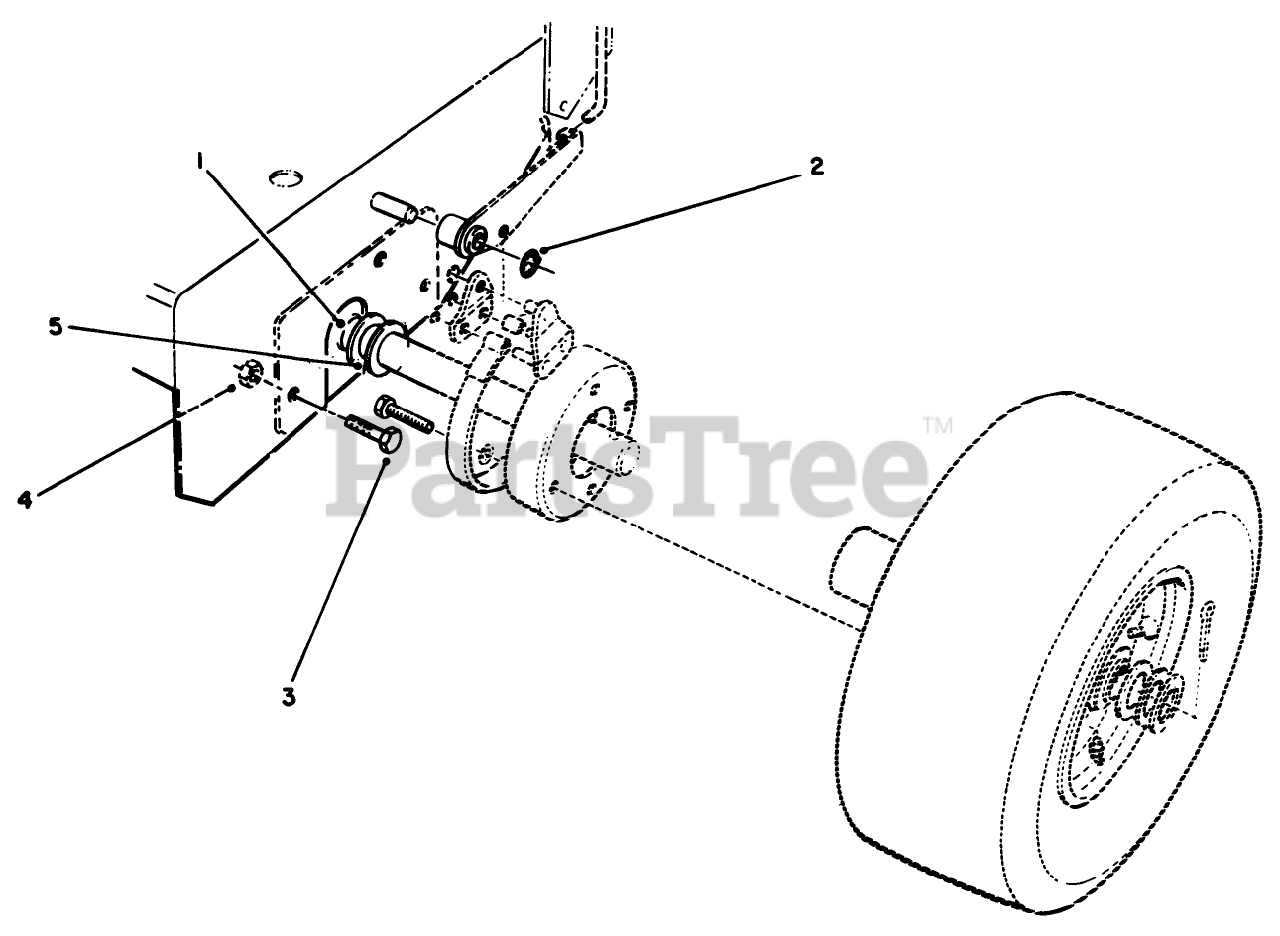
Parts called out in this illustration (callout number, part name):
1	AXLE WA
2	RING-RETAINING
3	SCREW-HH
4	NUT-LOCK, NI
5	WASHER-WHEEL
